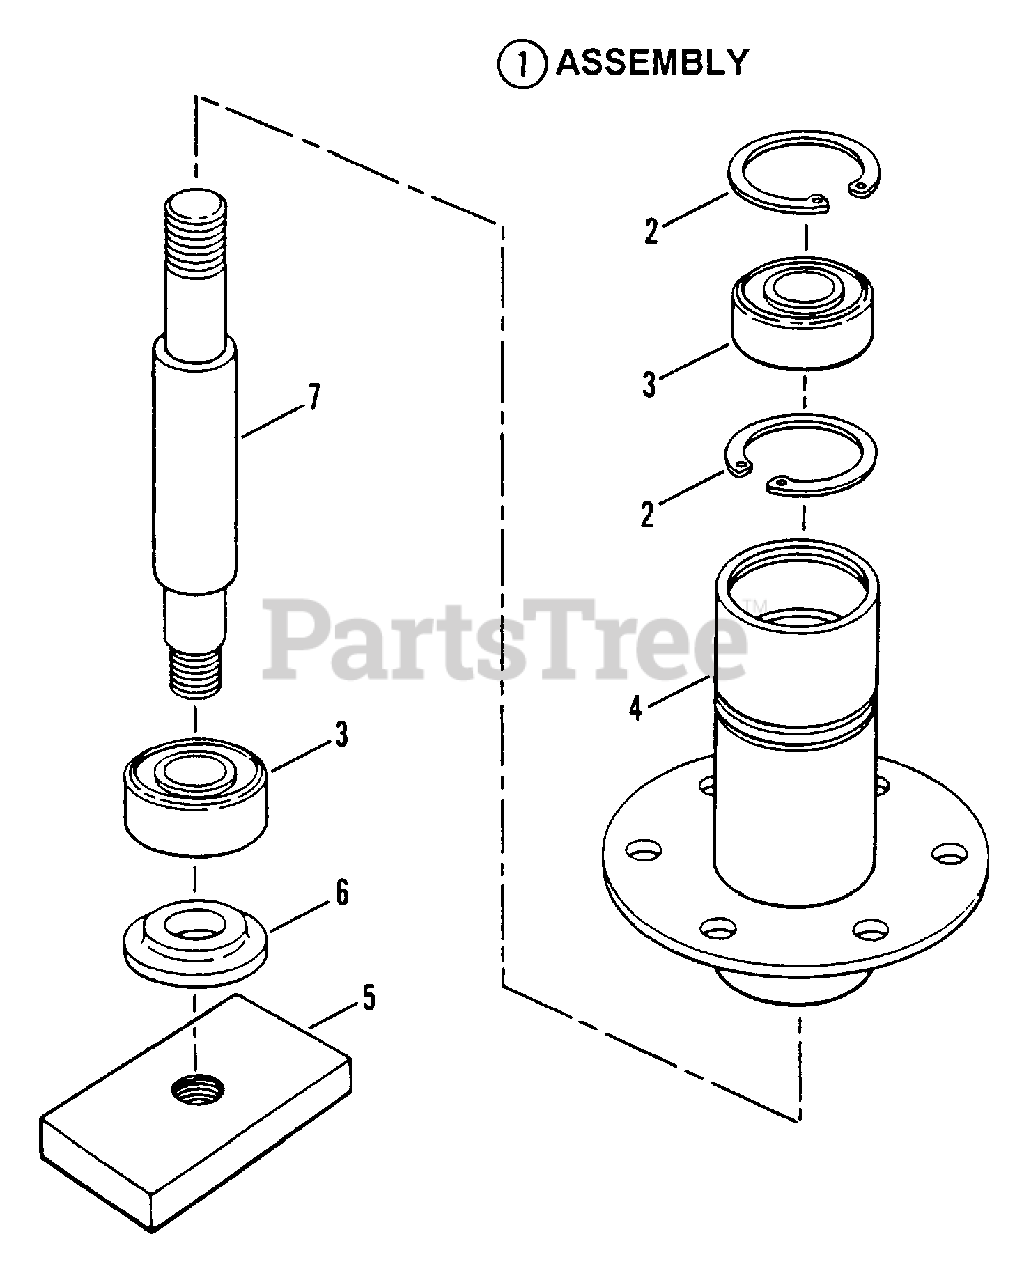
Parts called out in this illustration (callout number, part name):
1	ASSEMBLY, Spindle Housing, 42" Cutting Deck
2	RING, Retaining
3	BEARING, Spindle
4	HOUSING, Spindle
5	HOLDER, Blade
6	WASHER, Spindle
7	SPINDLE 6.5"
